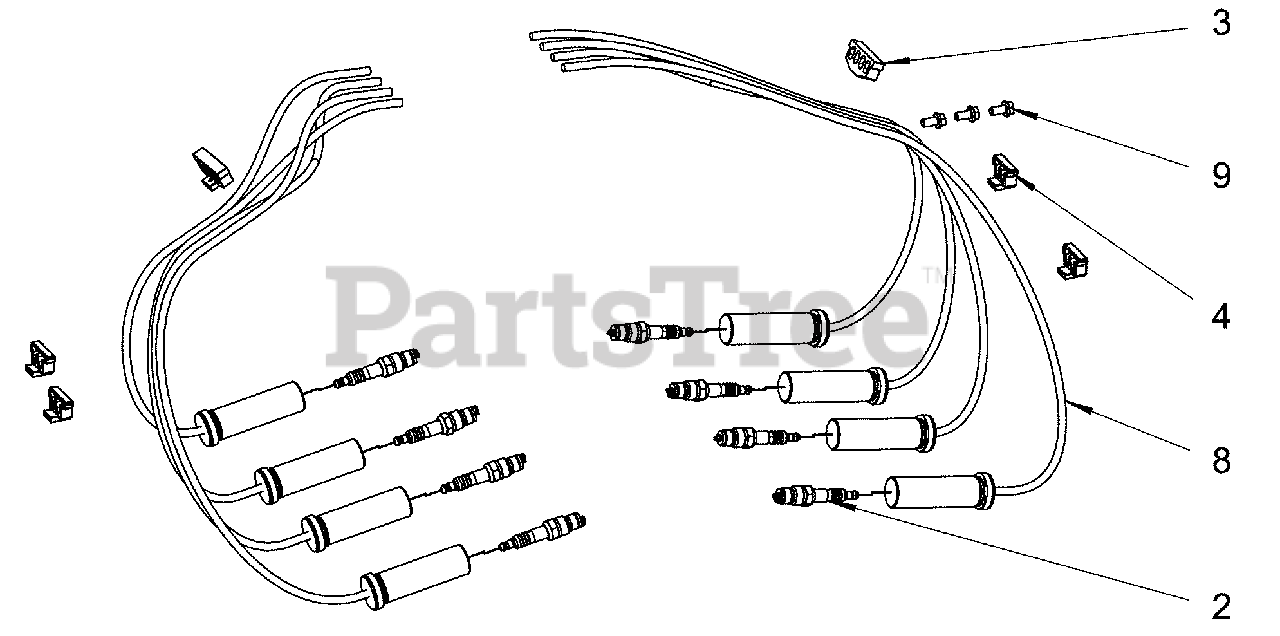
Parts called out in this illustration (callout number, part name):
3	* 4 WIRE RETAINER
4	* 2 WIRE RETAINER
8	SPARK PLUG WIRE
9	* BOLT
